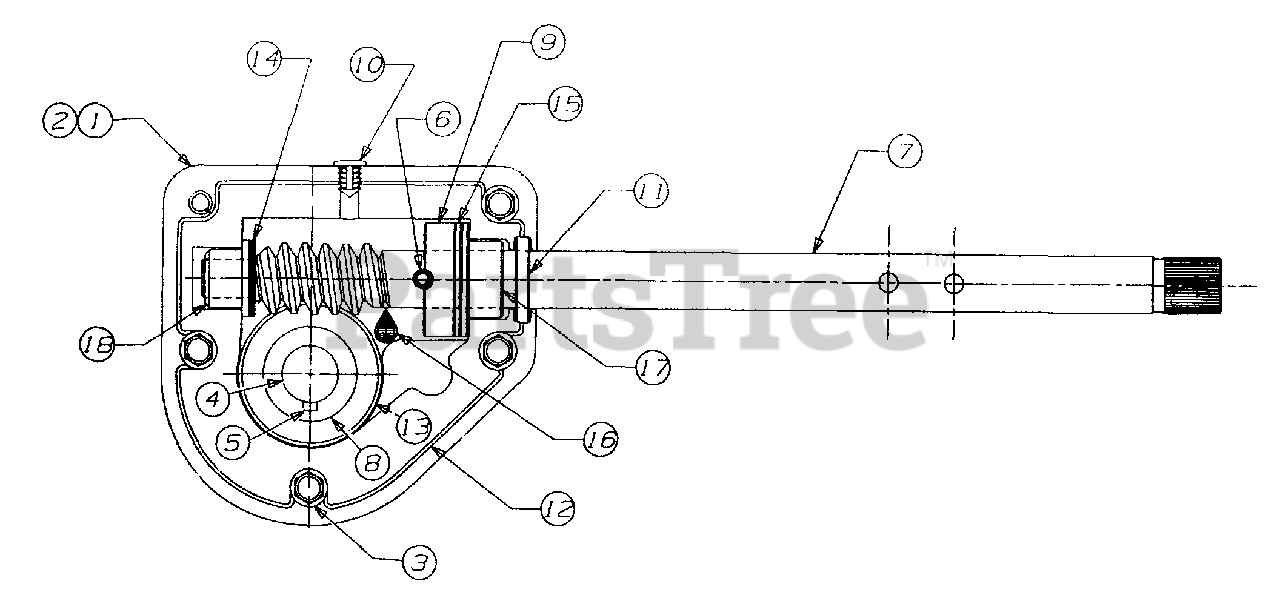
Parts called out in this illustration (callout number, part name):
1	Housing - R.H.
2	Housing - L.H.
3	Screw
4	Axle, Spiral
5	Key, Hi-Pro
6	Pin, Spiral
7	Worm, Shaft
8	Gear, Worm
9	Collar, Thrust
11	Seal, Oil
12	Loctite 5699, Ultra
13	Washer
14	Washer
15	Washer
16	Grease
17	Bearing Flange
18	Bearing Flange
